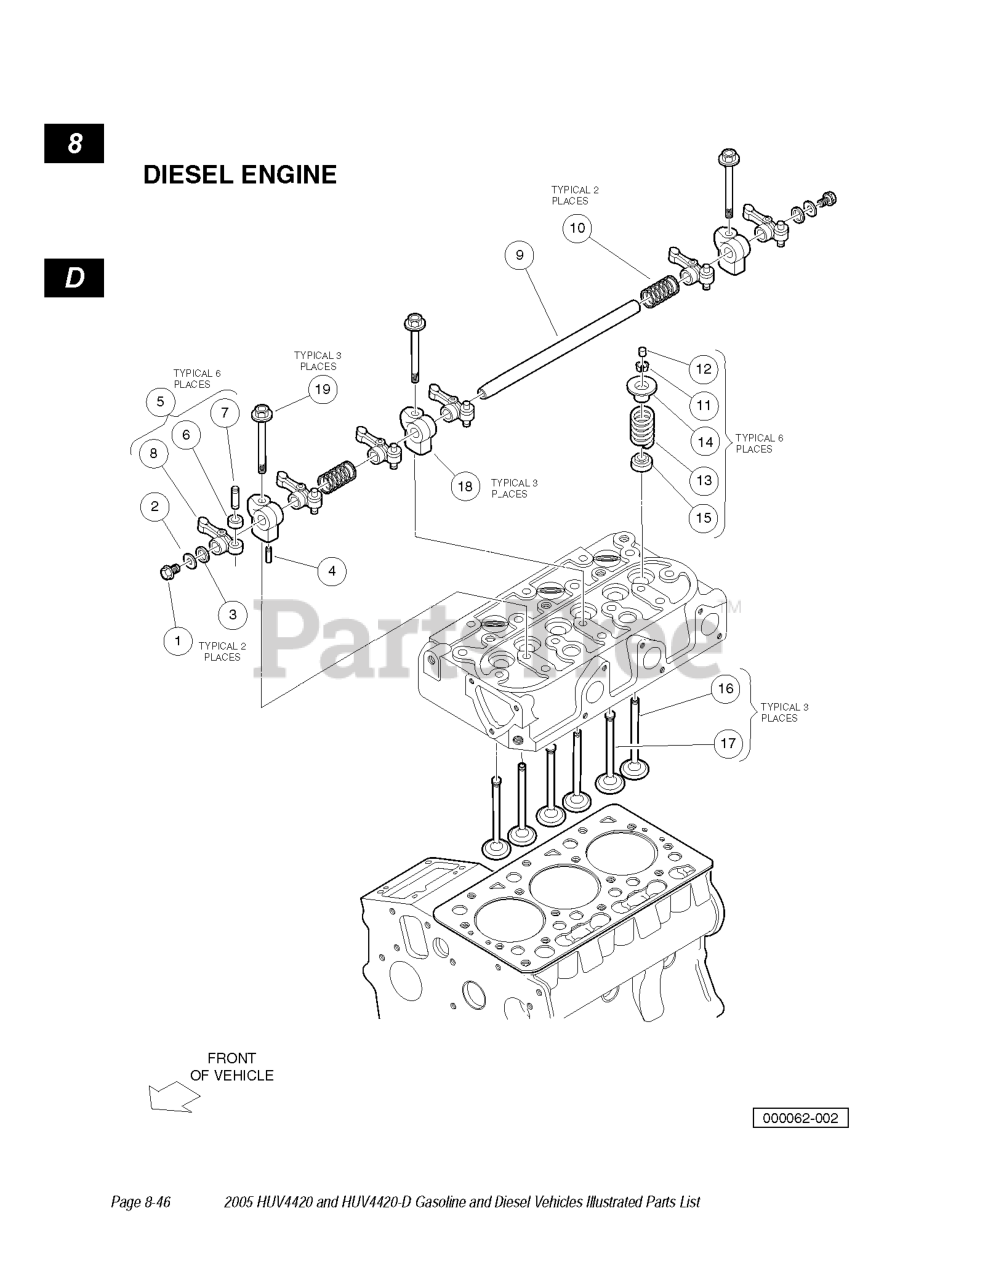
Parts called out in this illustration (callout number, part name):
1	BOLT, M6 X 1 X 8
2	WASHER, D722, PLAIN, ROCKER
3	WASHER, ROCKER ARM
4	PIN, SPRING, D722, ROCKER
5	ASSY ROCKER ARM
7	SCREW-ADJUSTING
9	SHAFT, ROCKER ARM
10	SPRING, ROCKER ARM
11	COLLET, VALVE SPRING, SET
12	CAP, VALVE, D722
13	SPRING, VALVE
14	RETAINER, SPRING
15	SEAL, VALVE STEM
16	VALVE, EXHAUST
17	VALVE, INLET
18	BRACKET-ROCKER ARM
